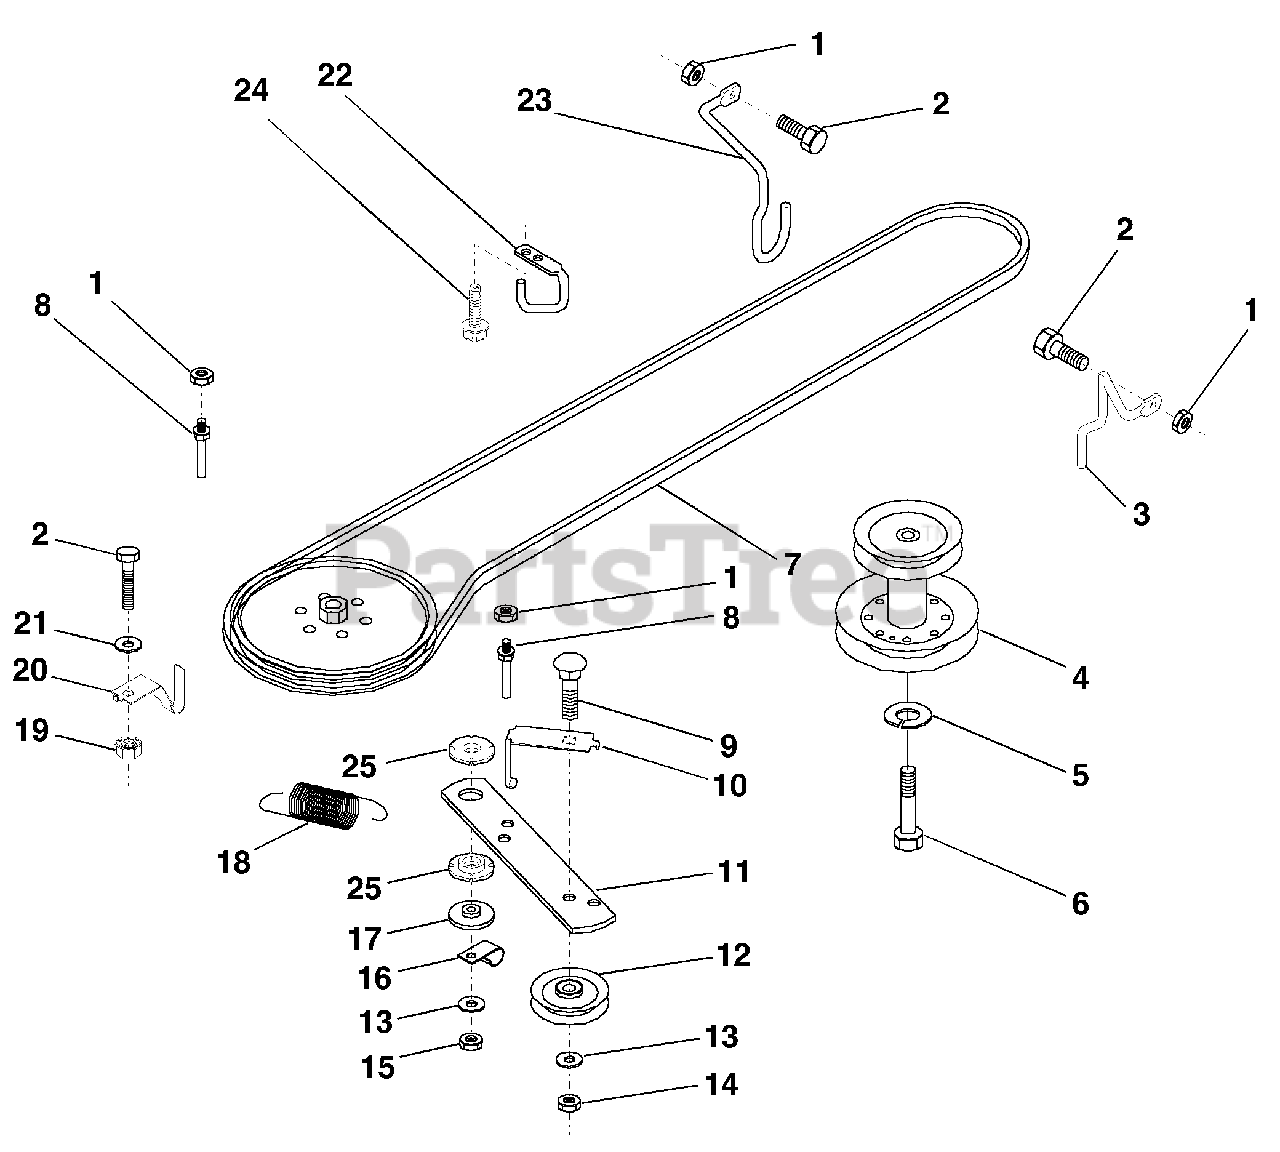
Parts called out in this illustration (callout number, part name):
1	Nut, Crownlock 5/16-18
2	Bolt, Hex Hd 5/16-18 UNC x 3/4
3	Keeper,Mower Drive, R. H.
4	Pulley, Engine
5	Washer, Lock 7/16
6	Bolt Hex 7/16-20 Gr. 5
7	Traction, V-Belt Drive
8	Keeper, T/A Ground Drive Belt
9	Bolt, Carr. 3/8-16 UNC x 1-1/2
10	Keeper, Belt Ground Drive Idler
11	Arm, Ground Drive Clutch
12	Idler, Flat
13	Washer 13/32 x 13/16 x 16 Ga.
14	Nut, Centerlock 3/8-16 UNC
15	Nut, Crownlock 3/8-16 UNC
16	Clip, Insulated
17	Spacer, Retainer
18	Spring Extension
19	Nut, Keps 5/16-18 UNC
20	Keeper, T/A Ground Drive Belt
21	Washer 11/32 x 5/8 x 16 Ga.
22	Keeper, Frame Ground Drive Belt
23	Keeper, Mower Drive, L. H.
24	Screw, Thd. Cut 1/4-20 x 1/2
25	Bushing Nylon Collered
